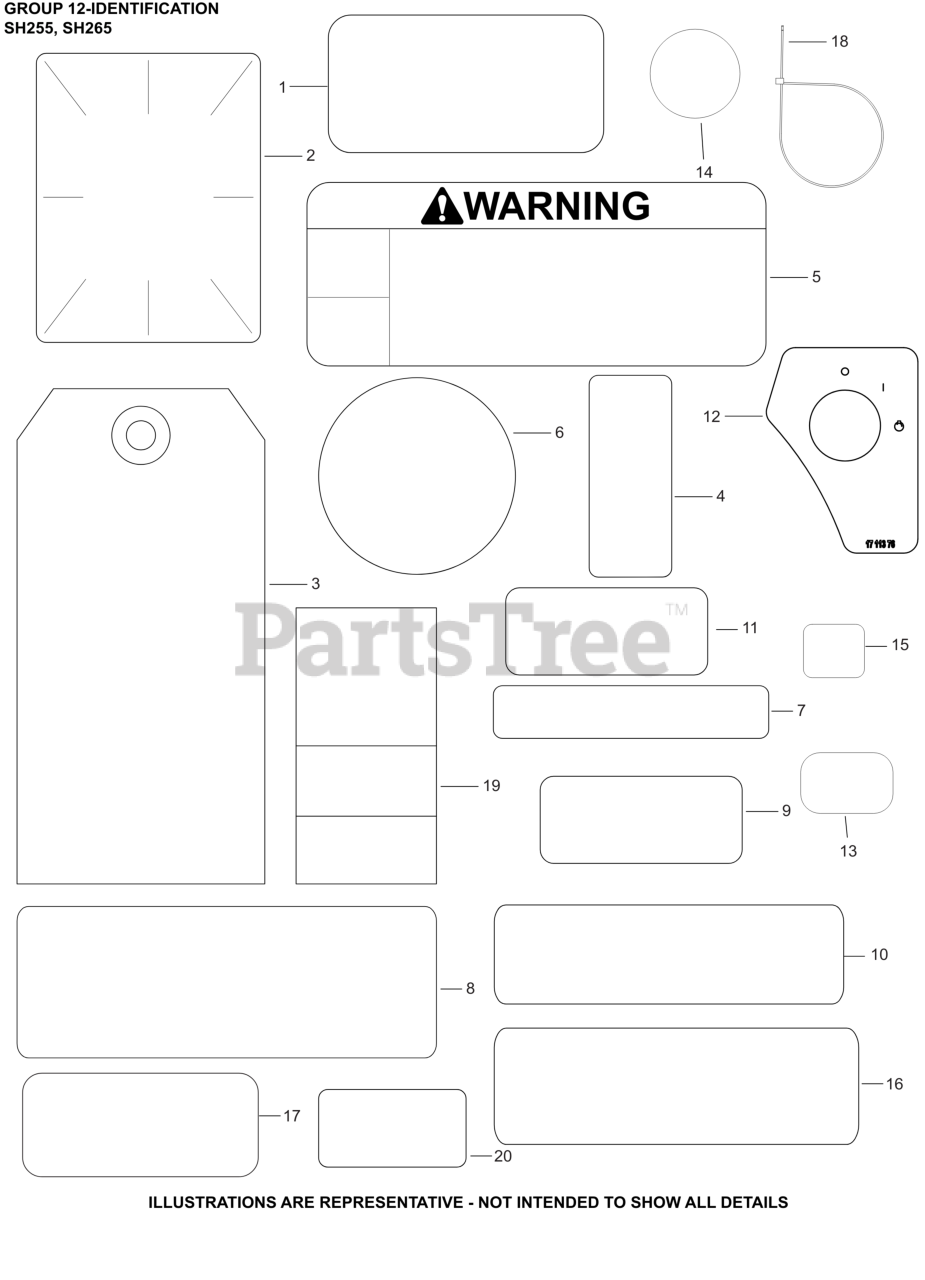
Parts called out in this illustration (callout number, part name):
1	LABEL, MAINTENANCE (CKY)
2	LABEL, CLEAR LAMINATION
3	TAG, HANG
3	TAG, PROP 65-OIL FILL ASSEMBLED
4	DECAL, FUEL/CHOKE - ON/OFF
5	DECAL, WARNING
6	LABEL, RECOIL 75MM
7	DECAL, THROTTLE
17	DECAL, ETHANOL WARNING
20	LABEL, HP SH270
